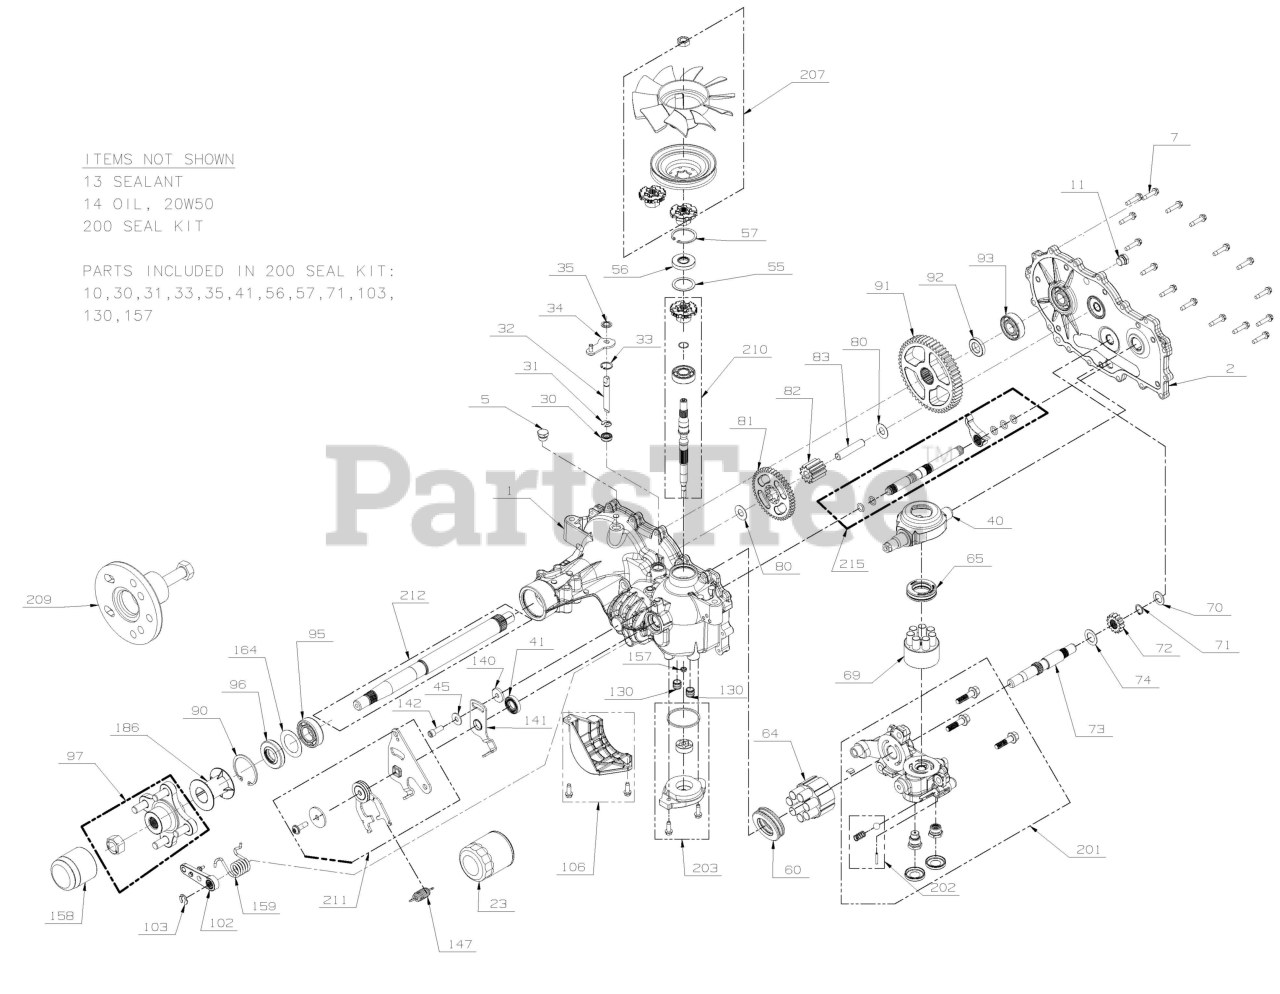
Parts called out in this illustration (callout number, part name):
1	KIT, MAIN HOUSING, RH, CHRG, CNTL
2	KIT, SIDE COVER RH
7	SCREW,HEX WASHER 1/4-20X1.125
13	SEALANT TUBE 10.1OZ.
23	OIL FILTER, TRANSMISSION
30	Seal, lip .375 x 375 x 325
31	RING. RETAINING
33	RING, RET .750
34	ARM, BYPASS
35	RING, RTNG .
40	TRUNNION, SWASHPLATE
55	WASHER 1.23X1.56X.04
57	RING, RET 1.56 INT
60	HG THRUST BEARING (51462)
64	HG 16CC CYLINDER BLOCK (71579)
65	BEARING. THRUST 30 X 52 X 13
69	ASSY, BLOCK 7 PISTON
70	WASHER .63X1.0X.05
71	RING, RET 62 EXT
72	GEAR, 14T (STEEL)
73	SHAFT, MOTOR
74	WASHER .71 X 1.16 X .04
80	WASHER .5X1.0X.032
82	GEAR, 11T (STEEL)
83	JACK SHAFT (PIN)
90	RING, RETAINING
91	GEAR, 54T
93	KIT, BEARING
95	BEARING, BALL 25.4 X 52 X 15
96	SEAL, LIP
97	KIT, HUB 4 BOLT
102	BRAKE ARM HG 71957
103	CLIP,BRAKE ARM HYDROGEAR 52027
106	KIT, FILTER GUARD
130	TUBE, CHARGE TRIPLE O-RING
141	ARM, NEUTRAL RIGHT
142	SHCS 5/16-24X1 PATCH
147	RTN SPRING HG 51605
157	KIT, GEROTOR SEAL
158	CAP, AXLE
159	SPRING, TORSION CCW
164	WASHER, 1.355 x 2.035 x .021 FLAT
186	TUBE, AXLE 2.03
200	KIT, SEAL
201	KIT, CENTER SECTION RH, CHARGE
202	KIT, CHARGE RELIEF
203	KIT, CHARGE
207	KIT, FAN / PULLEY
209	HUB PULLER 5 BLT
210	KIT, INPUT SHAFT
211	RTN KIT HYDROGEAR P/N 71597
212	SHAFT, AXLE
215	KIT, OUTBOARD, RH ROT A / LH ROT B
